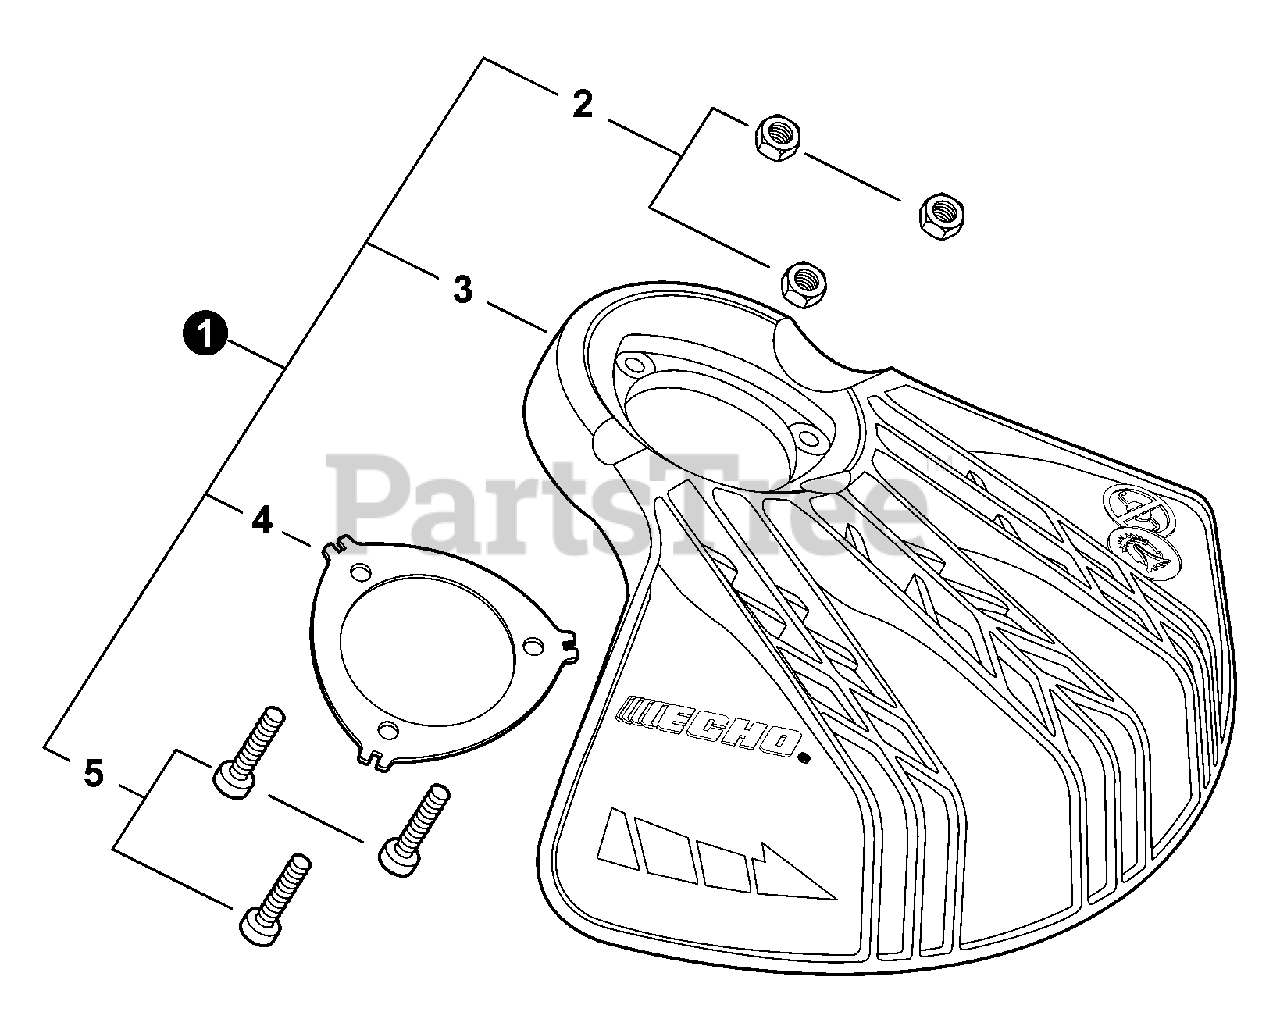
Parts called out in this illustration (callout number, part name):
1	DEBRIS SHIELD KIT - BLADE
2	NUT, LOCK M5
3	SHIELD, DEBRIS - BLADE
4	PLATE, SHIELD
5	BOLT, TORX 5×25
